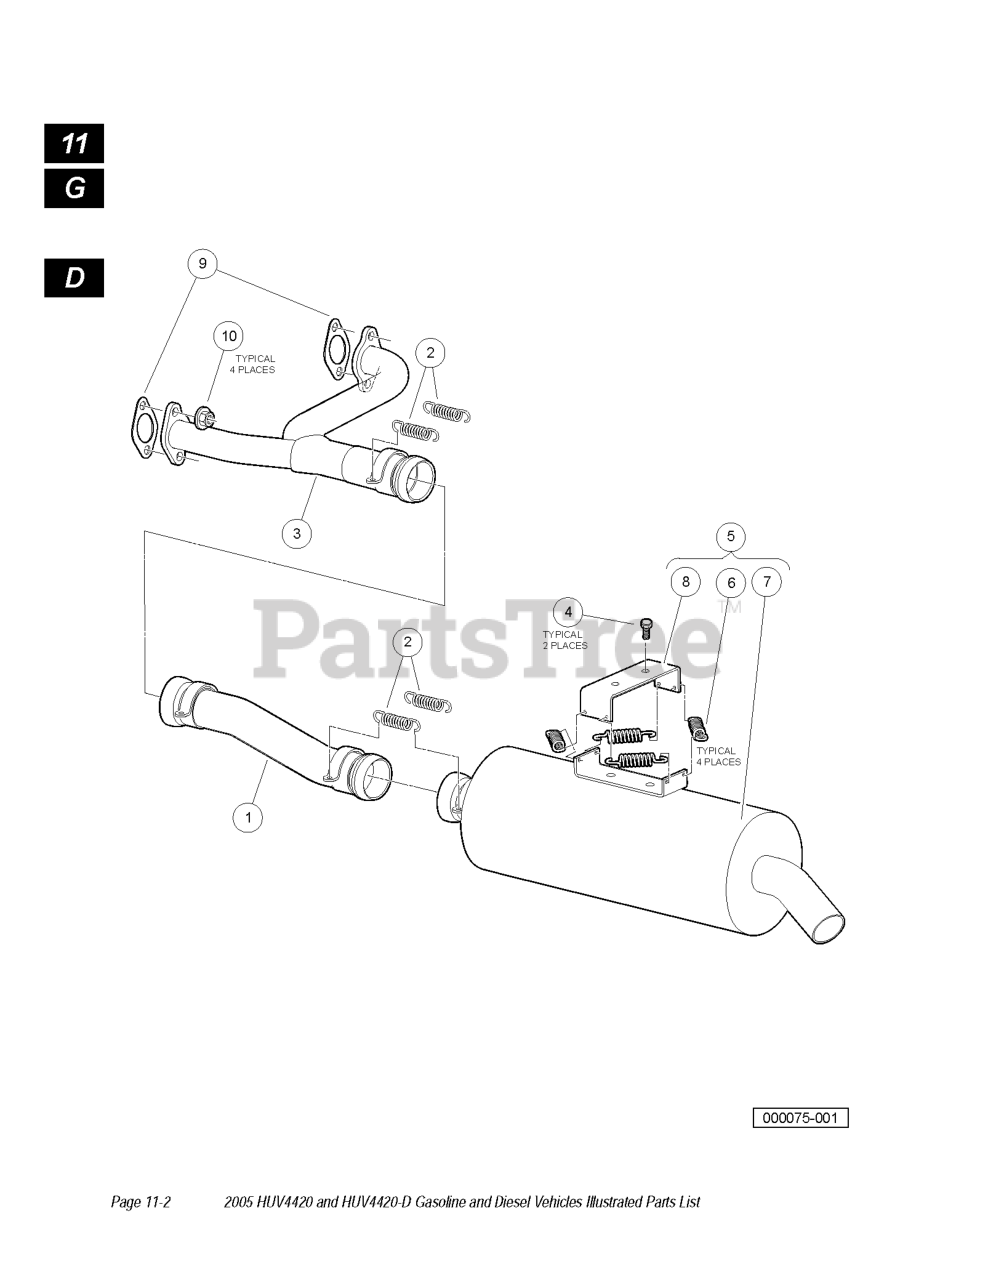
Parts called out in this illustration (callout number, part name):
1	PIPE, EXHAUST INTERMEDIATE
2	SPRING, EXHAUST
3	HEADER, EXHAUST, GAS
4	BOLT FLG, M8X1.25X16 LOCTITE
5	ASM, MUFFLER, AWD HOMOLOGATION
6	SPRING, EXHAUST
9	GASKET, EXHAUST, GAS
10	NUT, M8-1.25 FLANGED HEX
